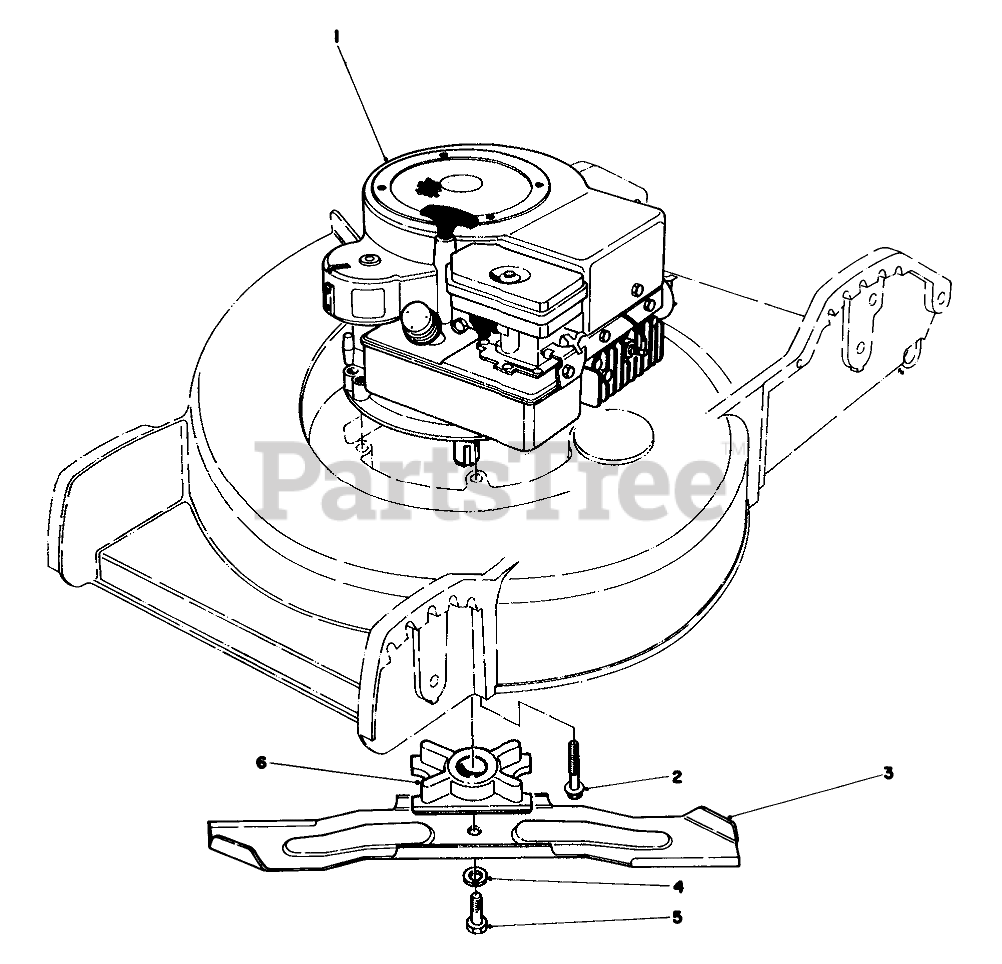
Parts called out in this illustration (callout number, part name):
1	Engine
2	3/8-16 X 2 CAPSCREW
3	Blade
4	WASHER-LOCK
5	SCREW-HH
6	BLADE RETAINER
